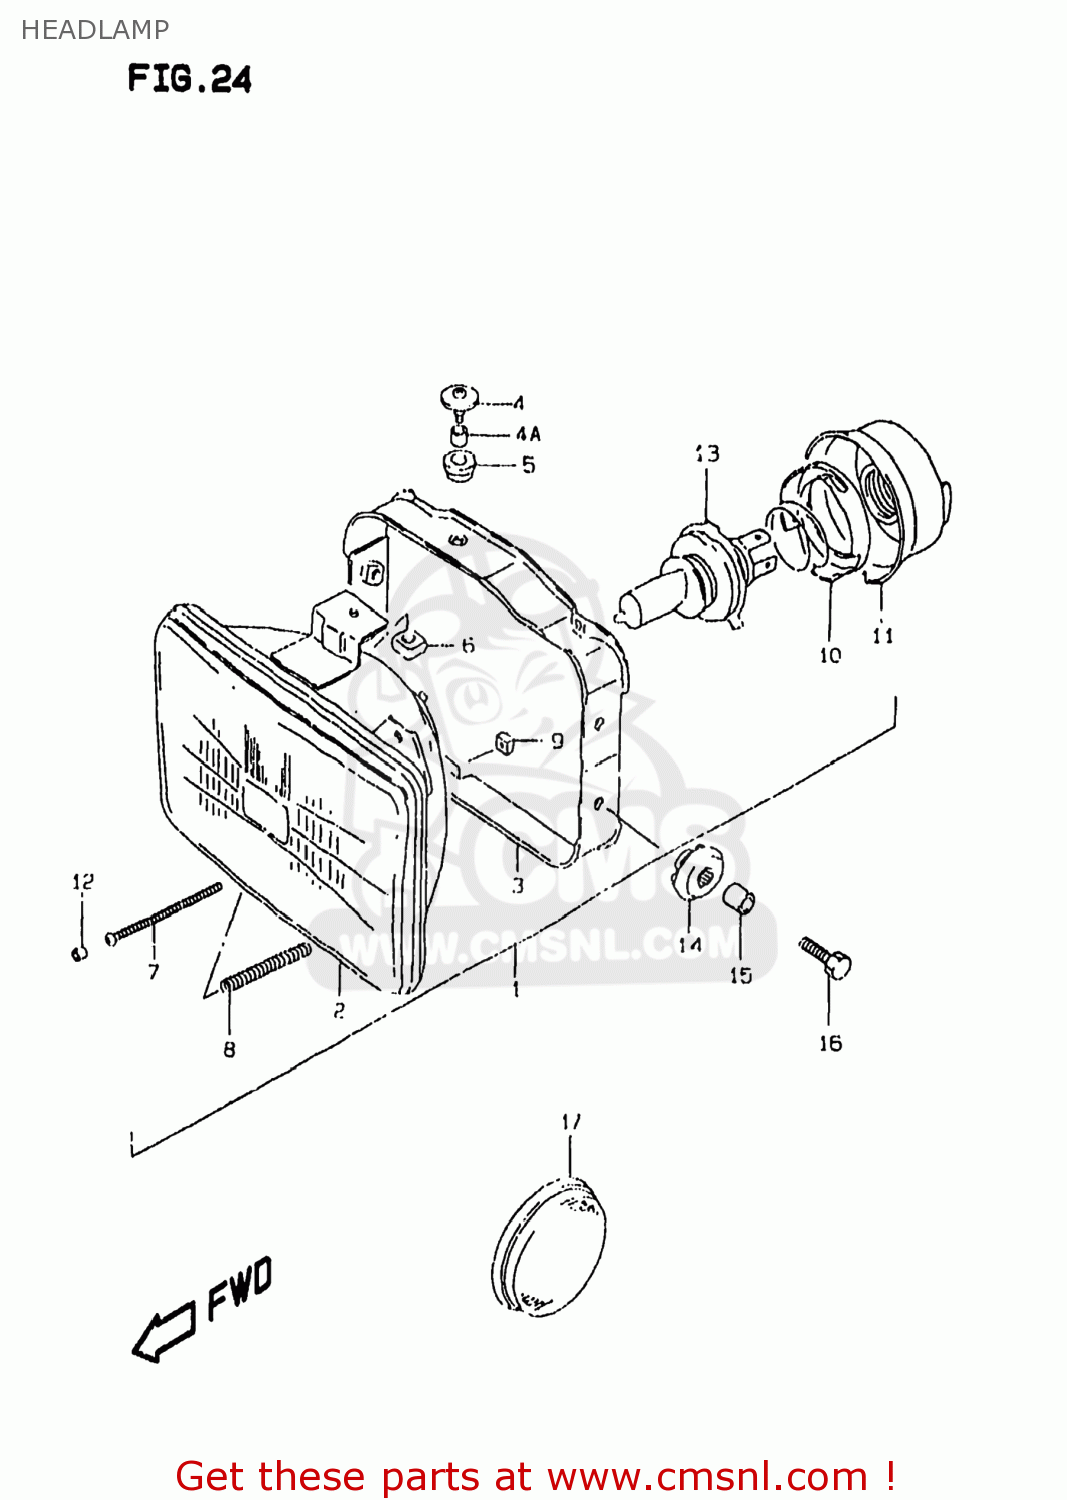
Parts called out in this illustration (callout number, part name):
1	HEADLAMP ASSEMBLY
2	LAMP UNIT
3	HOUSING
4	SCREW,MOUNTING
4A	SPACER
5	CUSHION
6	NUT
7	SCREW
8	SPRING
9	NUT
10	HOLDER,BULB
11	COVER,SOCKET
12	CAP,SCREW
13	BULB(12V60/55W,H4)
14	CUSHION
15	SPACER(6.3X9.1X11.5)
16	BOLT(6X20)
17	REFLECTOR,REFLEX FR
